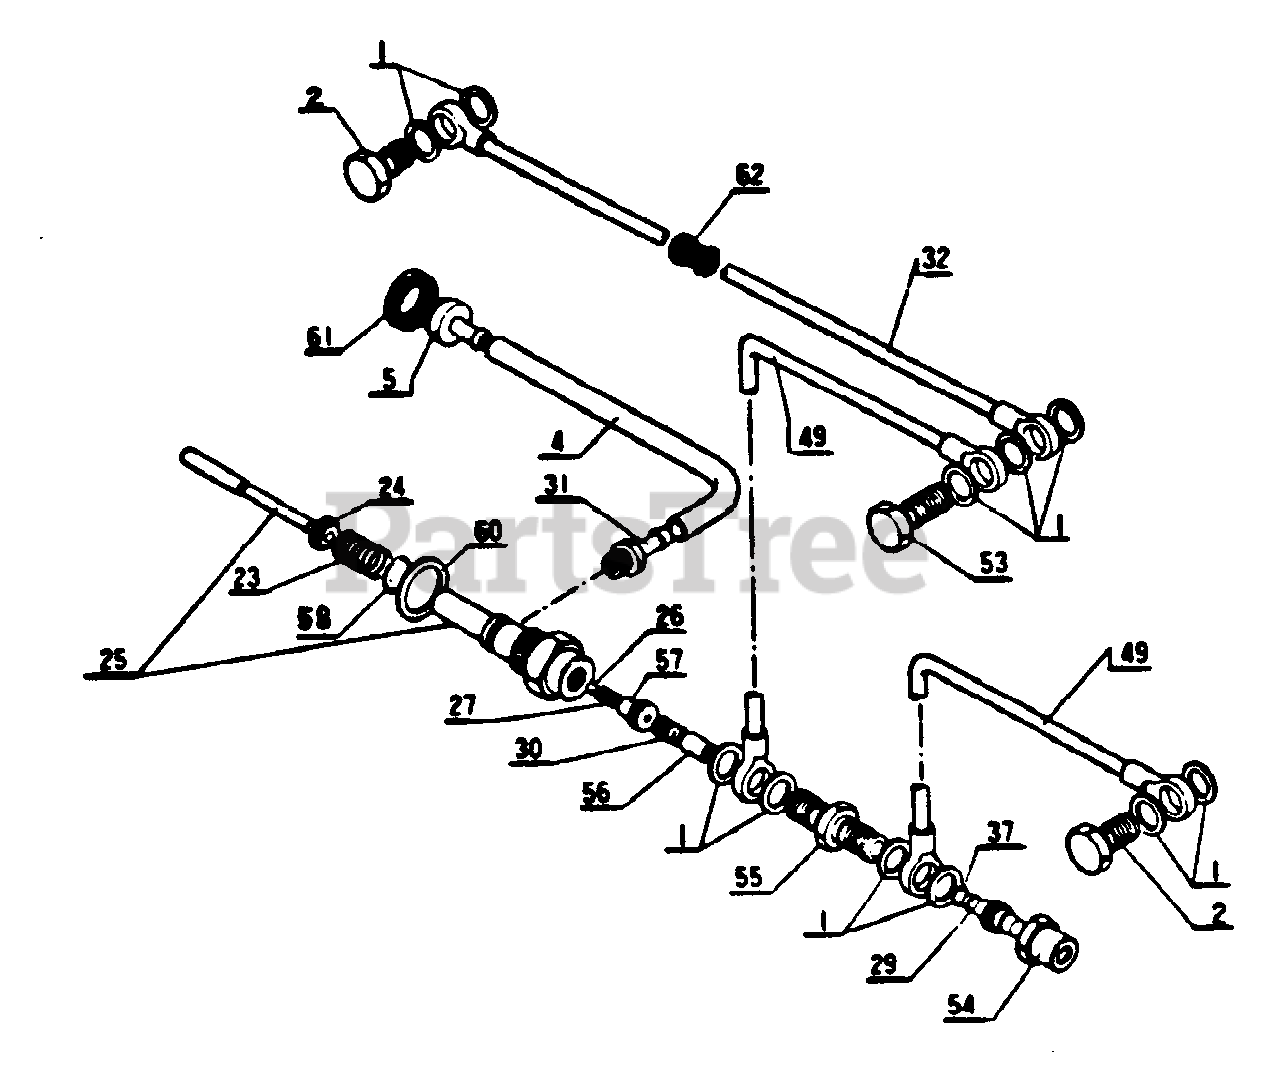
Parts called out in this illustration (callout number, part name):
1	GASKET
2	BOLT
4	PIPE, OIL - INNER
5	FILTER, OIL
23	SPRING
24	CASE, SPRING
25	CYLINDER, OIL
26	VALVE, BALL
27	SPRING, VALVE
29	SCREW, ADJUST
30	SPRING
31	NIPPLE
32	PIPE - OIL
37	O-RING
49	PIPE - OIL
53	BOLT
54	NUT, ADJUST
55	PUMP ADJUSTER
56	SPACER, PUMP
57	SEAT, VALVE
58	O-RING
60	PACKING
61	COVER, OIL FILTER
